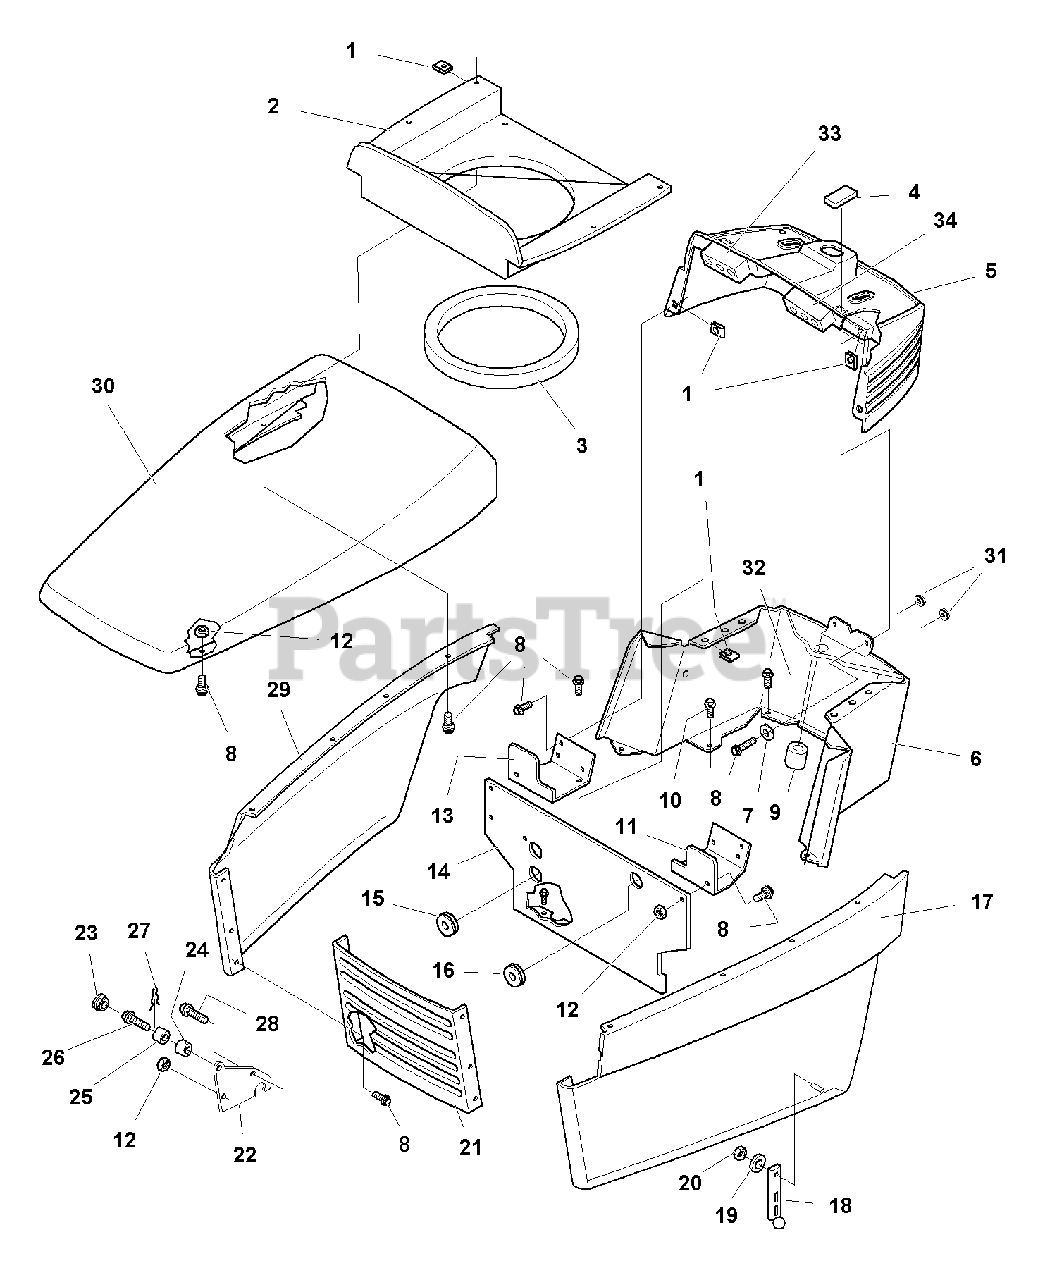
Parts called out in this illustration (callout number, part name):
1	PAL NUT, 1/4-20
3	MOLDING, Air Duct
4	PLUG, Hole, Electric Lift
5	DASH ASSEMBLY
6	DASH, Lower
7	WASHER, Plain, 1/4
8	CAPSCREW, Hex Flange Head, Whizlock, 1/4-20 x 5/8
9	BUSHING, Nylon
10	CAPSCREW, Taptite, 1/4-20 x 1/2
11	SUPPORT, Bulkhead, LH
12	NUT, Hex Nylon Lock, 1/4-20
13	SUPPORT, Bulkhead, RH
14	BULKHEAD
15	GROMMET, Wire Harness
16	GROMMET, Bulkhead
17	SIDE PANEL ASSEMBLY, LH, Orange
17	SIDE PANEL ASSEMBLY, LH, Red
18	STRAP, Hood
19	WASHER, Special
20	NUT, Hex Nylon Lock, #10-24
21	GRILLE
22	HINGE, Hood
23	SPACER, Hood
25	PIVOT, Hood
26	CAPSCREW, Taptite, 5/16-18 x 1
27	CLIP, Hairpin
28	CAPSCREW, Taptite, 5/16-18 x 5/8
29	SIDE PANEL ASSEMBLY, RH, Orange
29	SIDE PANEL ASSEMBLY, RH, Red
30	HOOD, Orange
30	HOOD, Red
32	CAPSCREW, Taptite, 1/4-20 x 3/8
33	INDICATOR DASH DECAL, RH
34	INDICATOR DASH DECAL, LH
